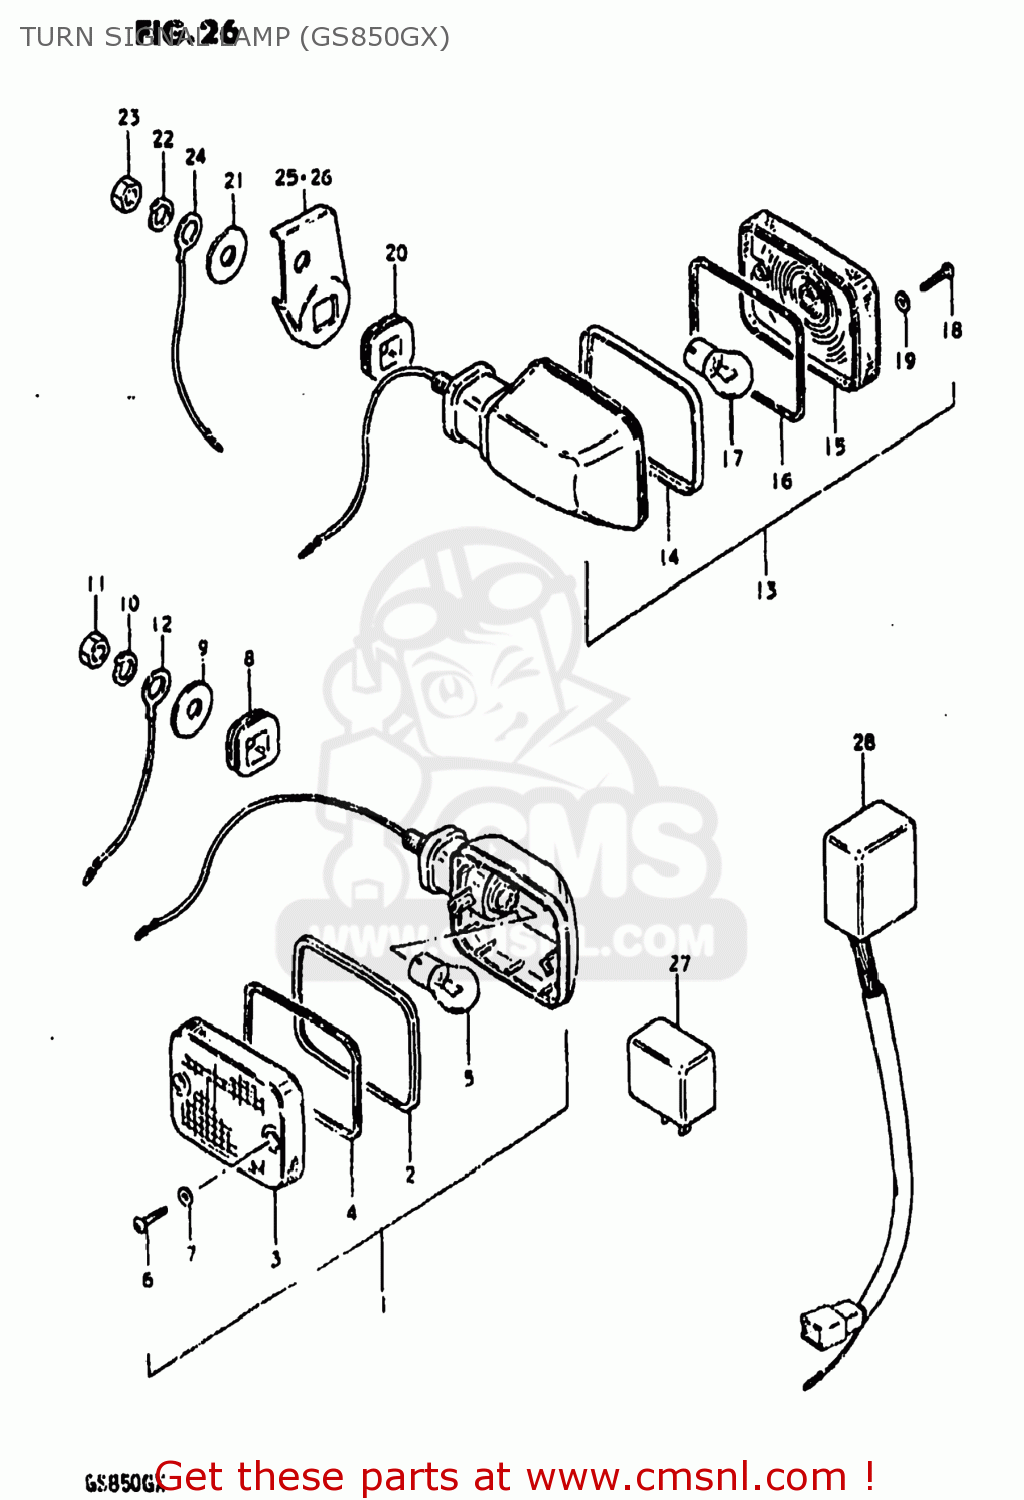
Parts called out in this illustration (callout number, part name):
1	LAMP ASSEMBLY,FRONT TURN SIGNAL
2	RIM
3	LENS
4	GASKET (NAS)
5	BULB(12V23W,STANLEY,A4577A)
6	SCREW
7	GASKET (NAS)
8	CUSHION
9	WASHER (10.5X30X2.3)
10	WASHER,LOCK
11	NUT
12	LEAD WIRE,EARTH
13	LAMP ASSEMBLY,FRONT TURN SIGNAL
14	RIM
15	LENS
16	GASKET (NAS)
17	BULB(12V23W,STANLEY,A4577A)
18	SCREW
19	GASKET (NAS)
20	CUSHION
21	WASHER (10.5X30X2.3)
22	LOCK WASHER
23	NUT
24	LEAD WIRE,EARTH
25	BRACKET,RR TURNSIGNAL LAMP,R
26	BRACKET,RR TURNSIGNAL LAMP,L
27	RELAY ASSY,TURNSIGNAL
28	UNIT,TURN SIGNAL CONTROL
